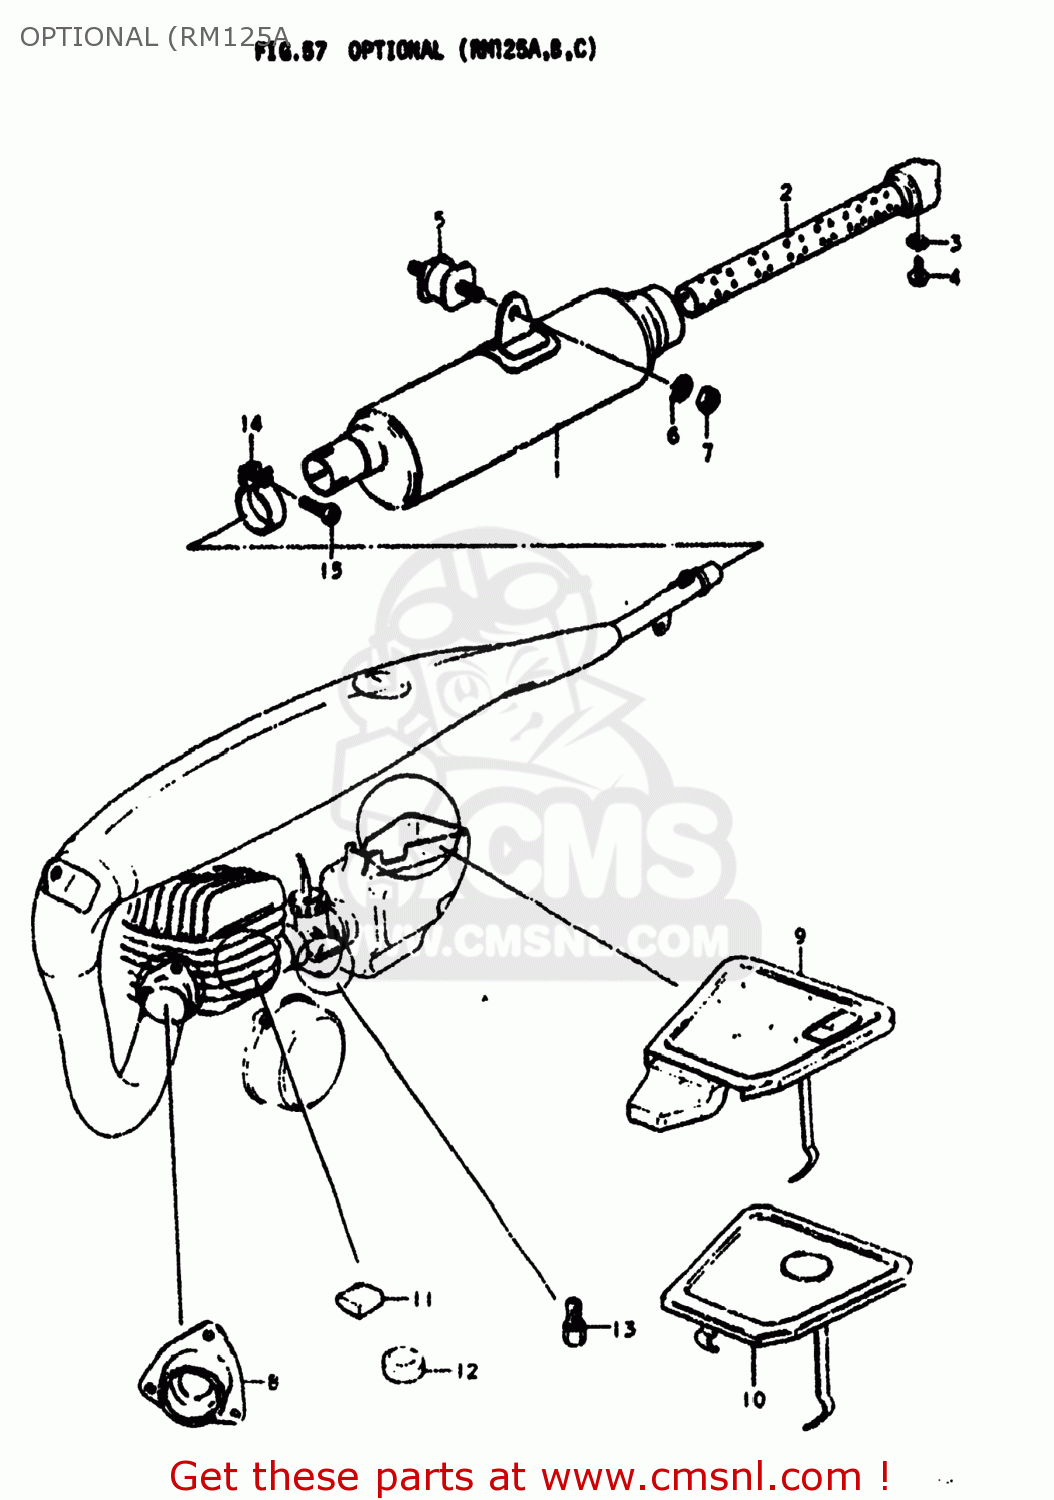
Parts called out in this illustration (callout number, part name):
0	OFF-ROAD SOUND KIT
1	MUFFLER ASSEMBLY
2	PIPE,MUFFLER BAFFLE
3	LOCK WASHER
4	SCREW
5	DAMPER,MUFFLER SUPPORT
6	LOCK WASHER
7	NUT
8	FLANGE,EXHAUST PIPE
9	CAP,AIR CLEANER
10	CAP,AIR CLEANER
11	PAD,CYLINDER
12	PAD,CYLINDER
13	JET
14	CLAMP
15	BOLT(6X20)
